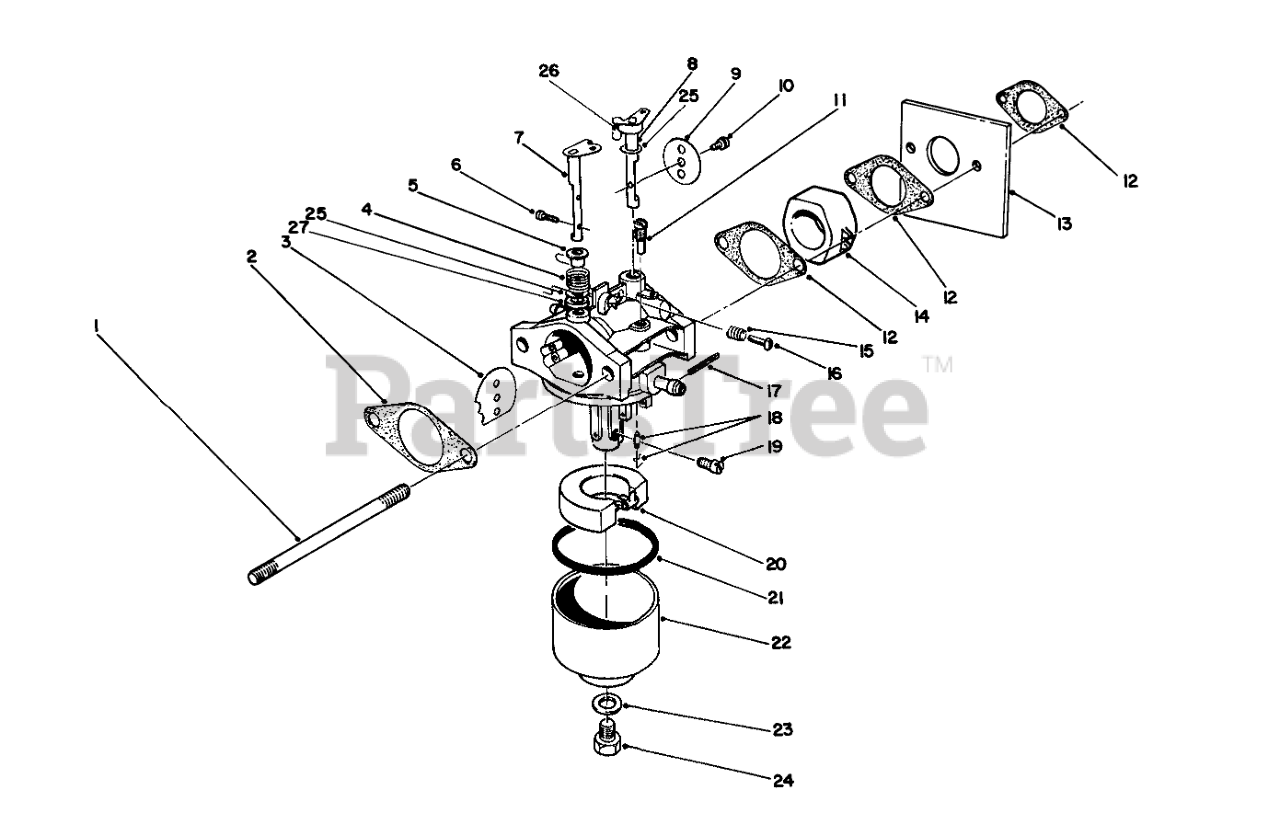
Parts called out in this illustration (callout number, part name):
1	STUD-CARBURETOR
2	GASKET-AIR CLEANER
3	PLATE
4	SPRING
5	BUSHING
6	SCREW
7	SHAFT-CHOKE
8	SHAFT
9	PLATE
10	Screw-Throttle
11	PILOT JET
12	GASKET-CARB
13	SHIELD-CARBURETOR
14	INSULATOR
15	SPRING-PILOT SCREW
16	SCREW
17	PIN-HINGE
18	NEEDLE
19	JET-MAIN
20	FLOAT
21	GASKET
22	BOWL - FLOAT
23	GASKET
24	SCREW
27	PACKING
